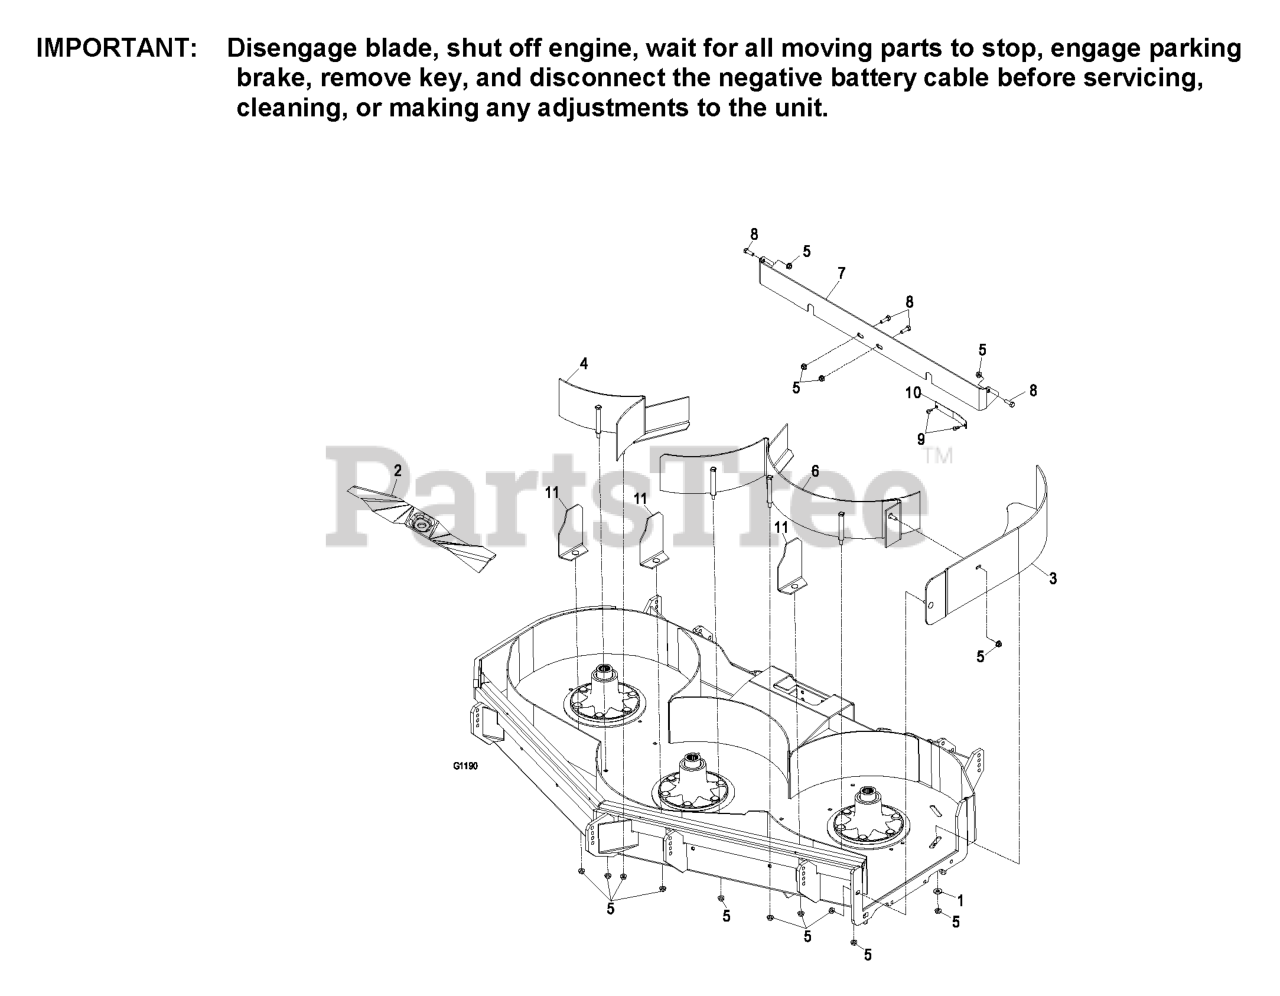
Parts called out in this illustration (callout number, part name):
1	WASHER-BELLEVILLE
3	ASM,MULCH SKIRT RH465
4	ASM,MULCH BAFFLE LH465
5	NUT-HHF, SMOOTH
6	ASM,MULCH BAFFLE RH465
7	PLATE,MULCH REAR 465/505/
8	SCREW-HH
9	SCREW-TP
10	BRACKET,MULCH FILL LHP
11	ASM,BLOCKER PLATE 465/505
